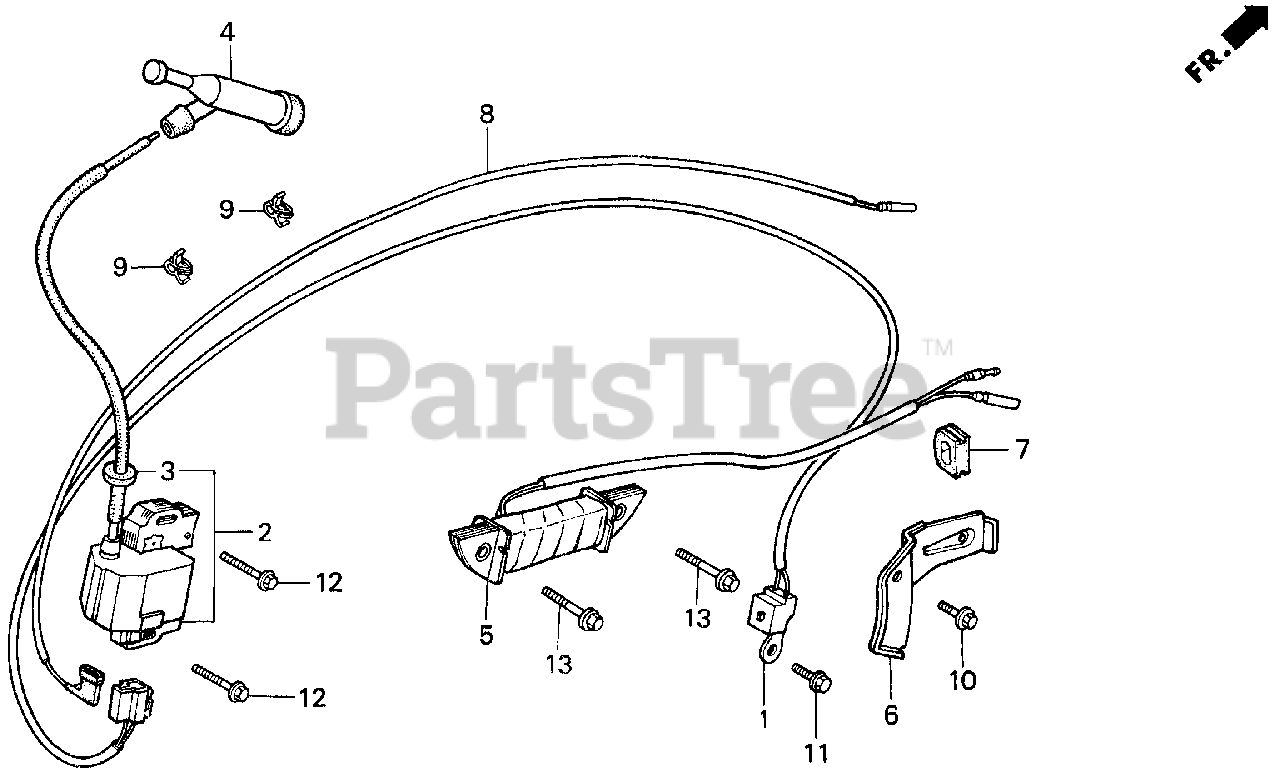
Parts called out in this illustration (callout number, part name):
2	COIL ASSY., IGNITION
4	CAP ASSY., NOISE SUPPRESSOR
4	CAP ASSY., NOISE SUPPRESSOR (NGK Y-EZDB)
5	COIL ASSY., LAMP (12V/15W)
6	CLAMP, WIRE
7	GROMMET, WIRE
8	WIRE, STOP SWITCH (470MM)
9	HOLDER, STOP SWITCH WIRE
10	BOLT, FLANGE (6X12) (CT200)
12	BOLT, FLANGE (6X28)
13	BOLT, FLANGE (6X32)
